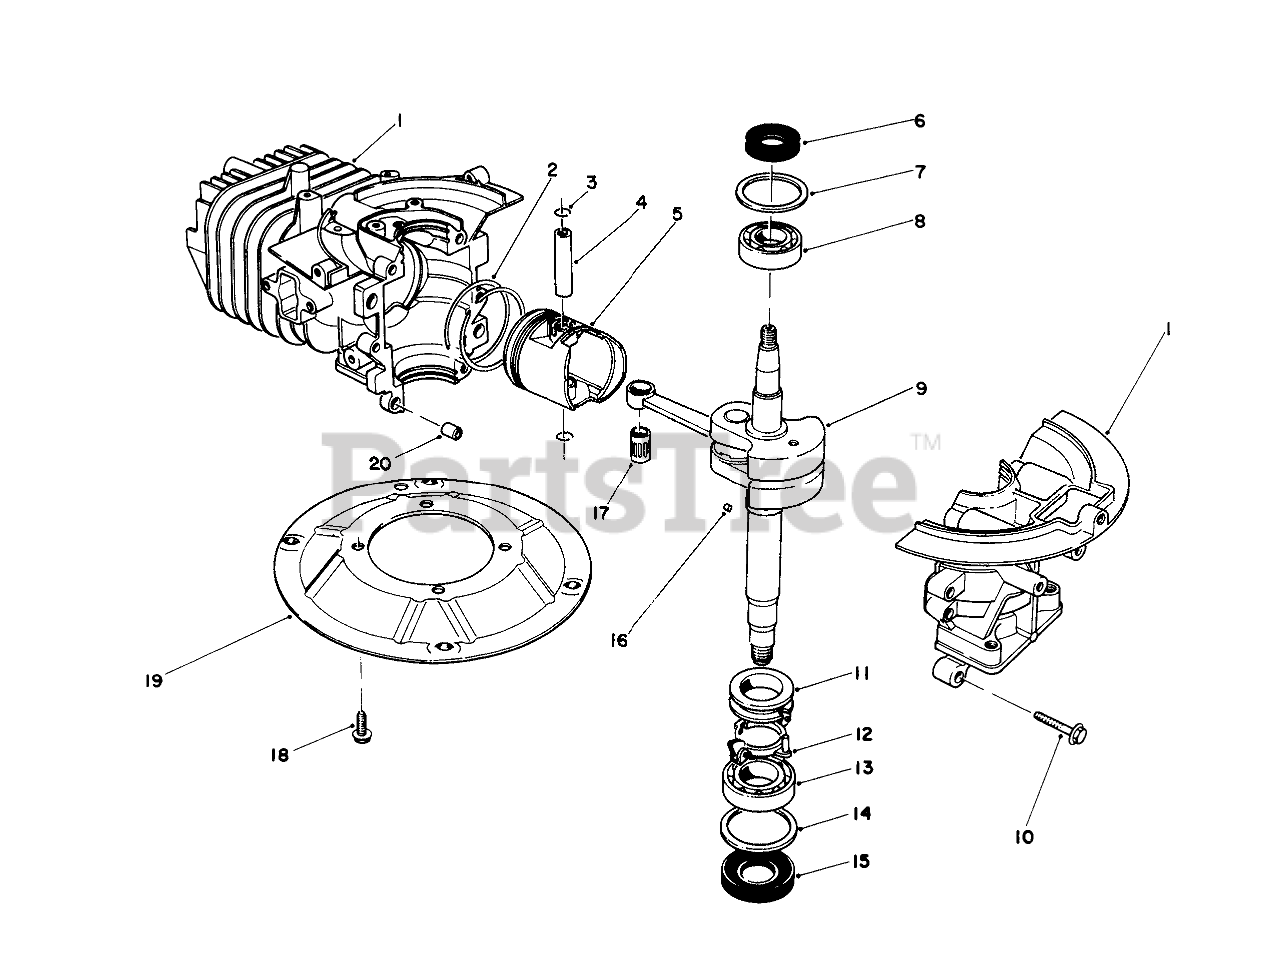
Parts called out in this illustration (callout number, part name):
1	CRANKCASE
2	RING SET
4	PIN-PISTON
5	Piston
6	OIL SEAL
7	WASHER-UPPER
8	BEARING-UPPER
9	CRANKSHAFT
11	SPACER
12	BRACKET
13	LOWER BRG
14	WASHER-LOWER
15	SEAL-OIL
17	BEARING
19	PLATE-MOUNTING
